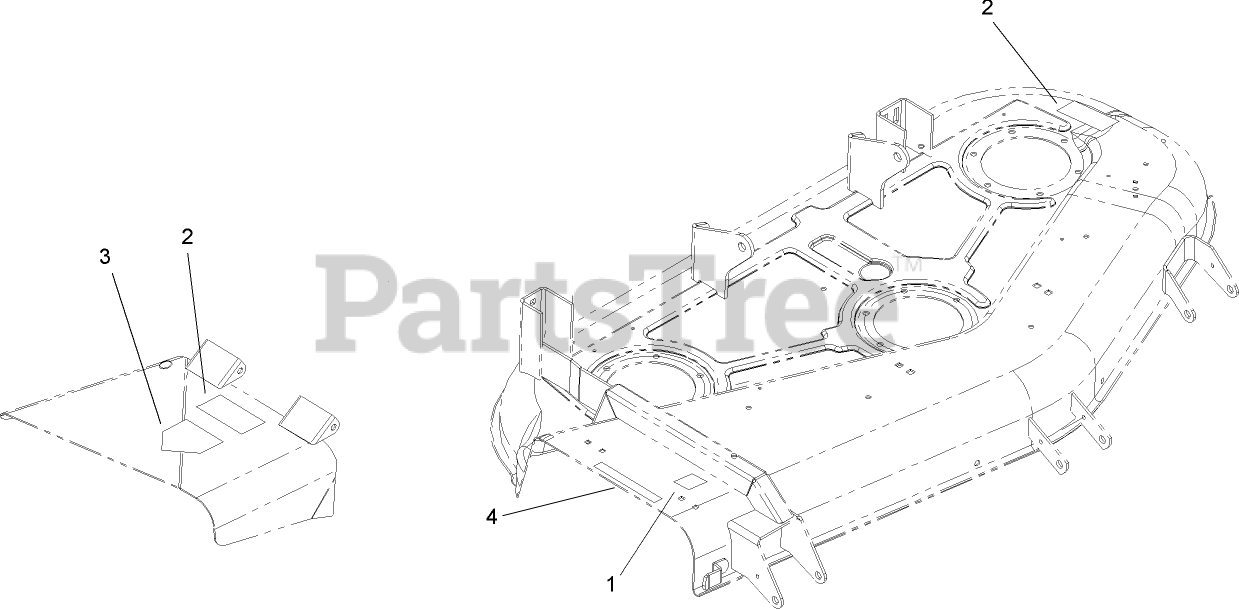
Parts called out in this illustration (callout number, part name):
1	DECAL-NOISE
2	DECAL-DANGER
3	DECAL-DANGER
4	DECAL-DANGER
